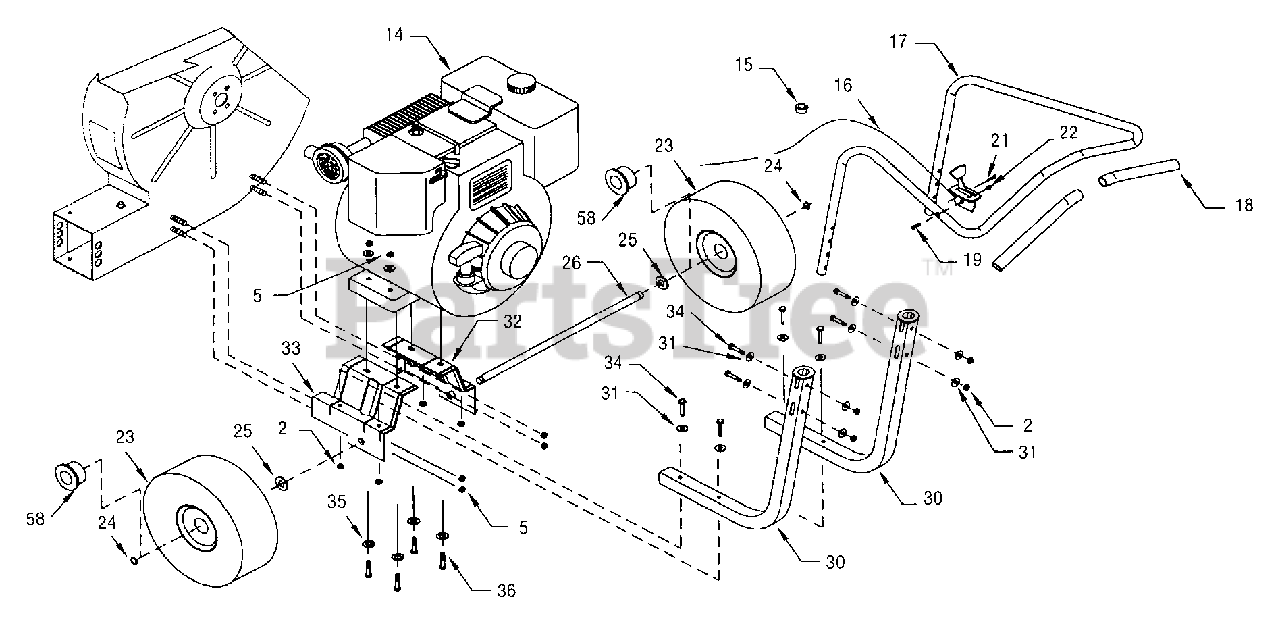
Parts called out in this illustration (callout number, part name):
2	5/16-18 Nylon Insert Nut
5	5/16-18 Serrated Flanged Lock Nut
14	5 HP Honda Engine Honda
15	Throttle Clip
16	Throttle Cable
17	Upper Handle
18	Grip (set of 2)
19	1/4-20 x 1 3/4 HHCS gr5
22	1/4-20 2-Way Lock Nut
23	Pneumatic Wheel Offset, 10 in. DIA
24	Retaining Ring
25	5/8 SAE Flat Washer
30	Lower Handle
31	5/16 Flat Washer
32	Deck, Right 5, 8
33	Deck, Left 5, 8
34	5/16-18 x 1 3/4 HHCS gr5
35	5/16 Regular Split Lock Washer
36	5/16-18 x 1 1/2 HHCS gr5
58	Pneumatic Wheel Bearing
